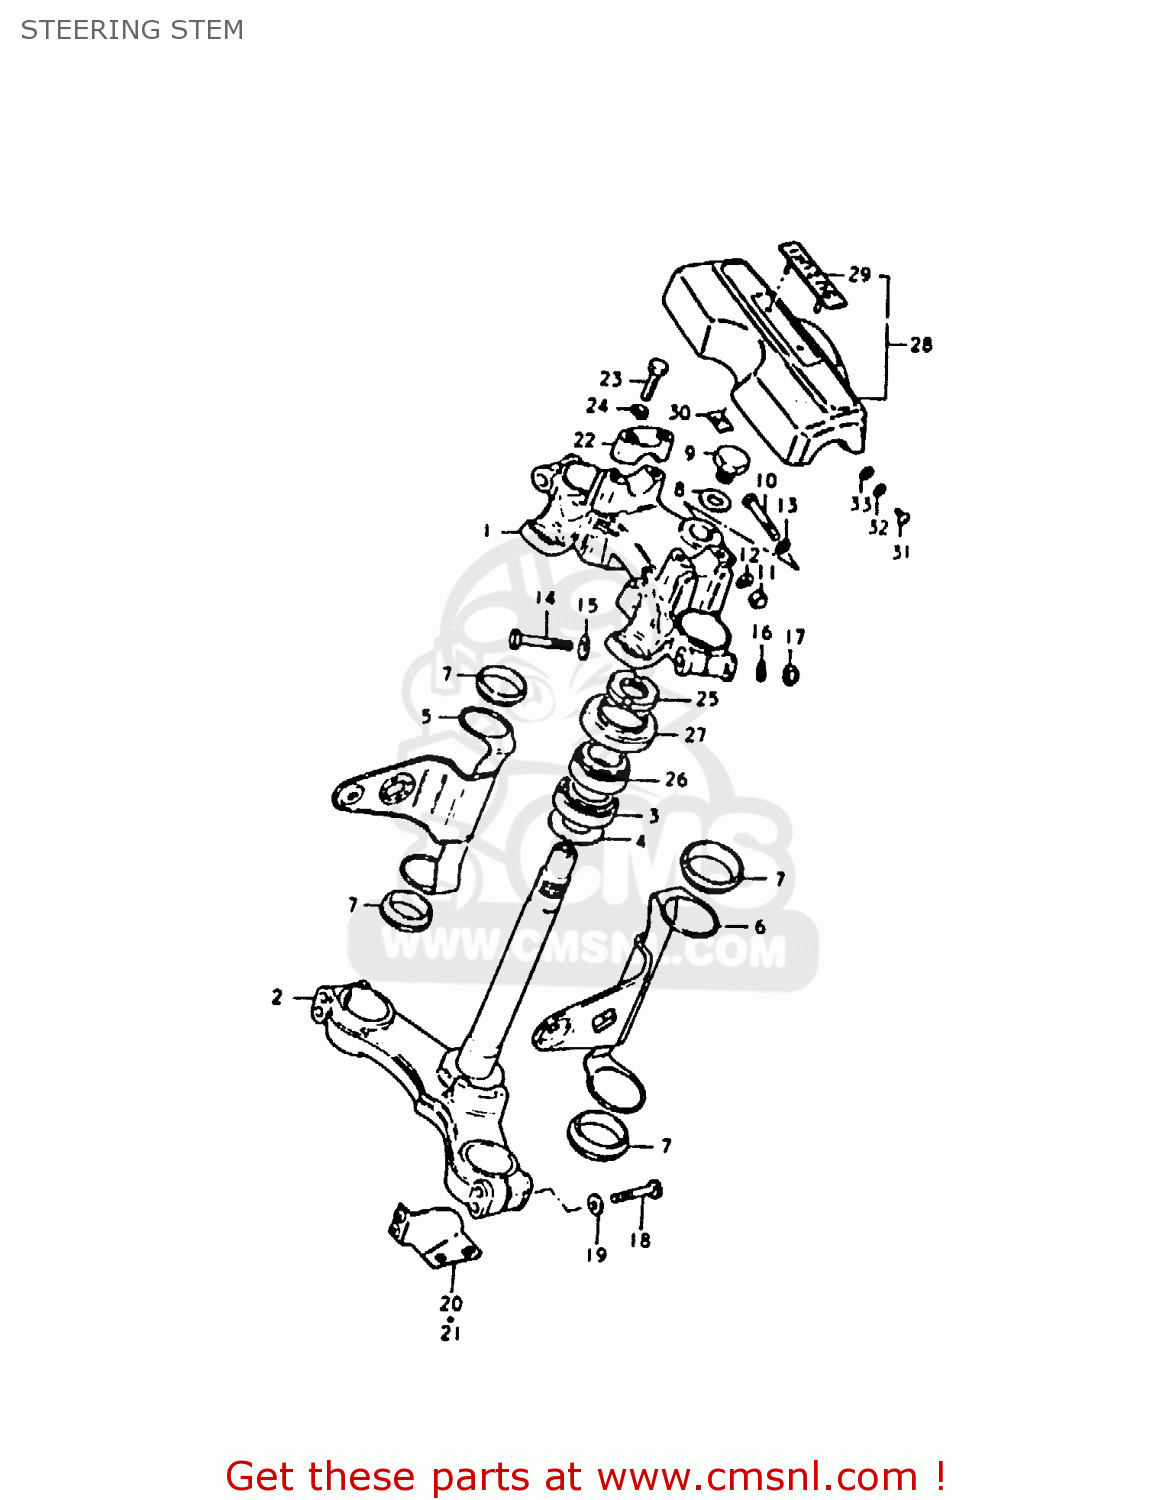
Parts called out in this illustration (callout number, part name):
1	HEAD,STEERING STEM
2	STEM,STEERING
3	BEARING
4	WASHER,THRUST
5	BRACKET,HEADLAMP,RIGHT
6	BRACKET,HEADLAMP,LEFT
7	CUSHION,HEADLAMP BRACKET
8	WASHER
9	NUT,FR FORK UPR BRACKET
10	BOLT 8X50
11	NUT
12	LOCK WASHER
13	WASHER
14	BOLT 10X60
15	WASHER
16	LOCK WASHER
17	NUT, LOWER LH
18	BOLT 8X55
19	WASHER
20	GUIDE, COWLING RH
21	GUIDE, COWLING LH
22	HOLDER,HANDLE(BLACK)
23	BOLT
24	LOCK WASHER
25	NUT,STEERING STEM(25X44X10)
26	TAPER,ROLLER BEARING
27	DUST SEAL,STEERING,UPPER
28	PAD,HANDLEBAR
29	EMBLEM,HANDLE COVER PAD
30	NUT
31	SCREW
32	LOCK WASHER
33	WASHER
